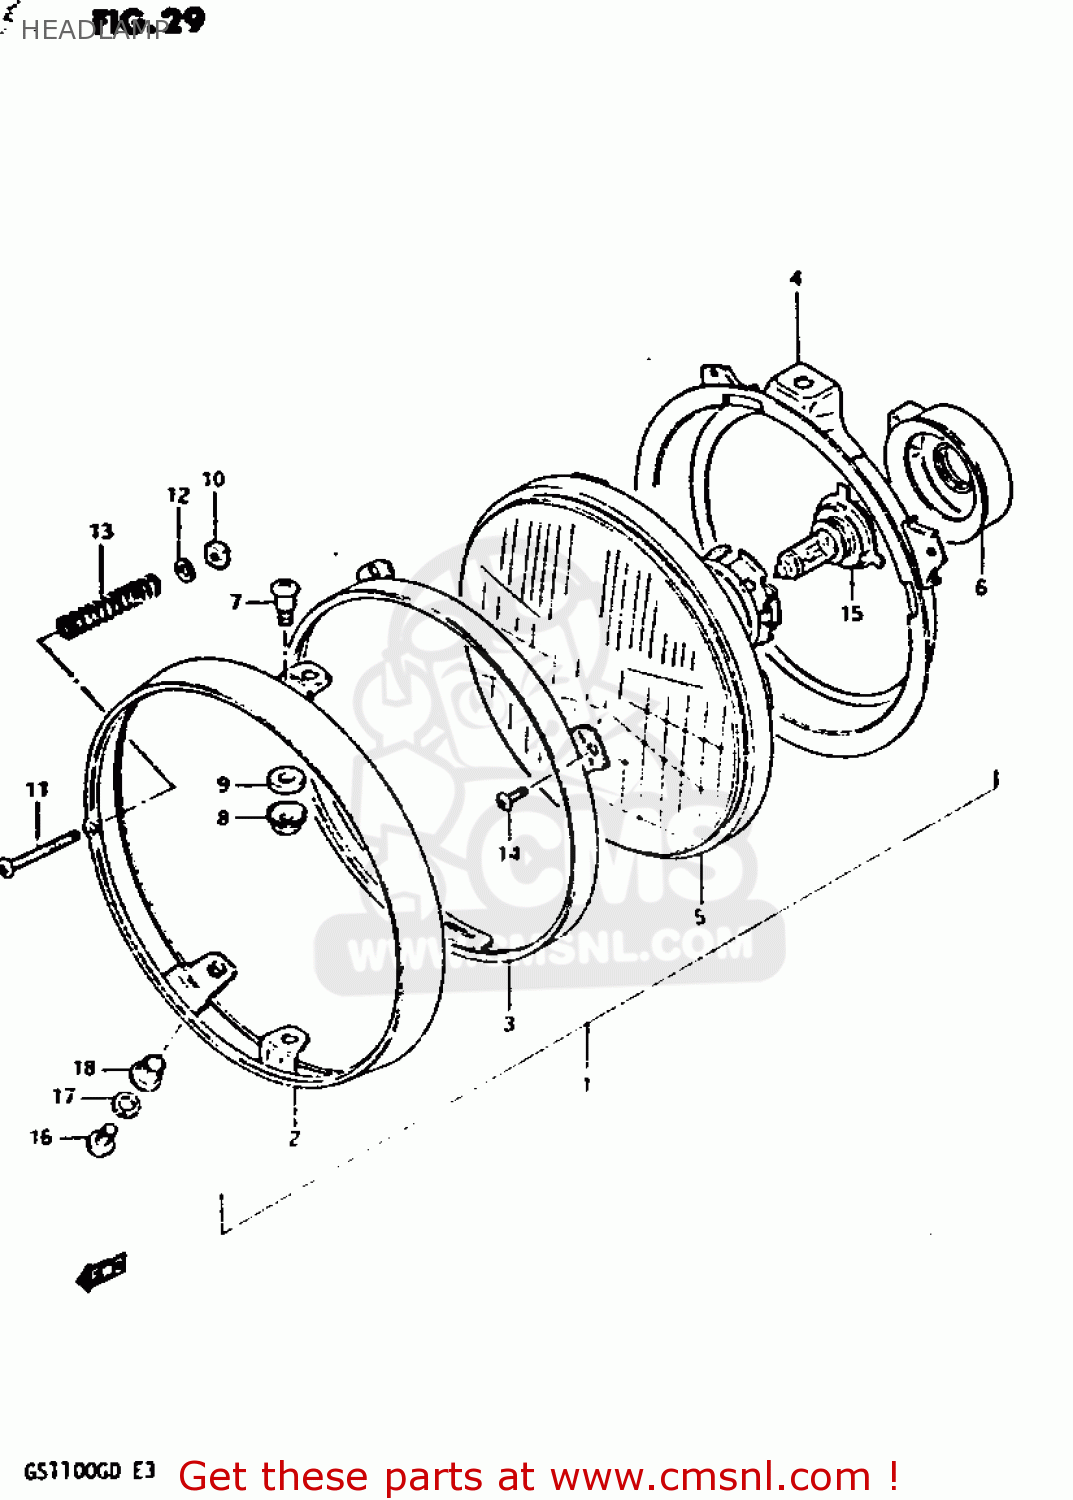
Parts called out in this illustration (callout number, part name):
1	HEADLAMP ASSEMBLY
2	RIM
3	RETAINER
4	RING,HEADLAMP UNIT
5	LAMP UNIT
6	COVER,HEADLAMP SOCKET
7	SCREW
8	NUT,ADJUSTING
9	SPACER
10	NUT
11	SCREW
12	WASHER
13	SPRING,HEADLAMP ADJUST
14	SCREW
15	BULB(12V60/55W,H4)
16	SCREW
17	WASHER,LOCK
18	WASHER
